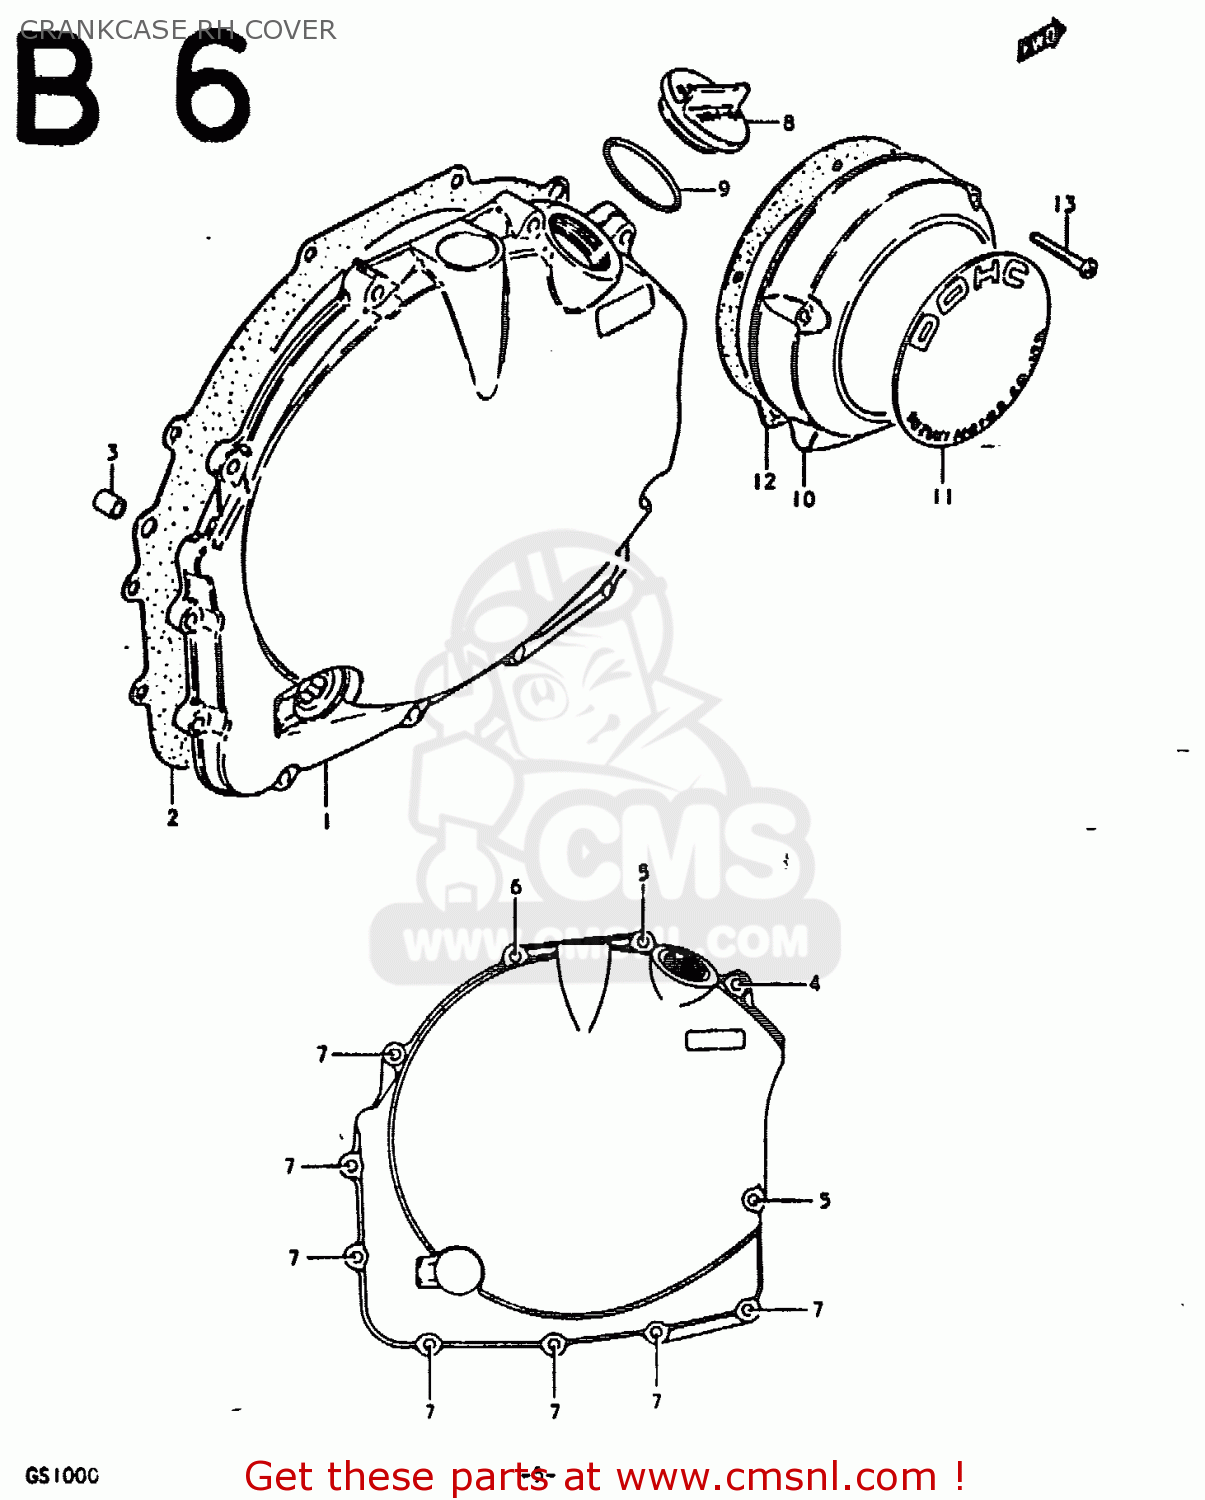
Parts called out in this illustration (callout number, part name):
1	COVER,CLUTCH
2	GASKET,CLUTCH COVER (MCA)
3	PIN
4	SCREW (6X35)
5	SCREW
6	SCREW
7	SCREW
8	CAP
9	O RING(D:2.2,ID:32)
10	COVER,CONTACT BREAKER
11	EMBLEM
12	GASKET,CONTACT BREAKER COVER (NAS)
13	SCREW
